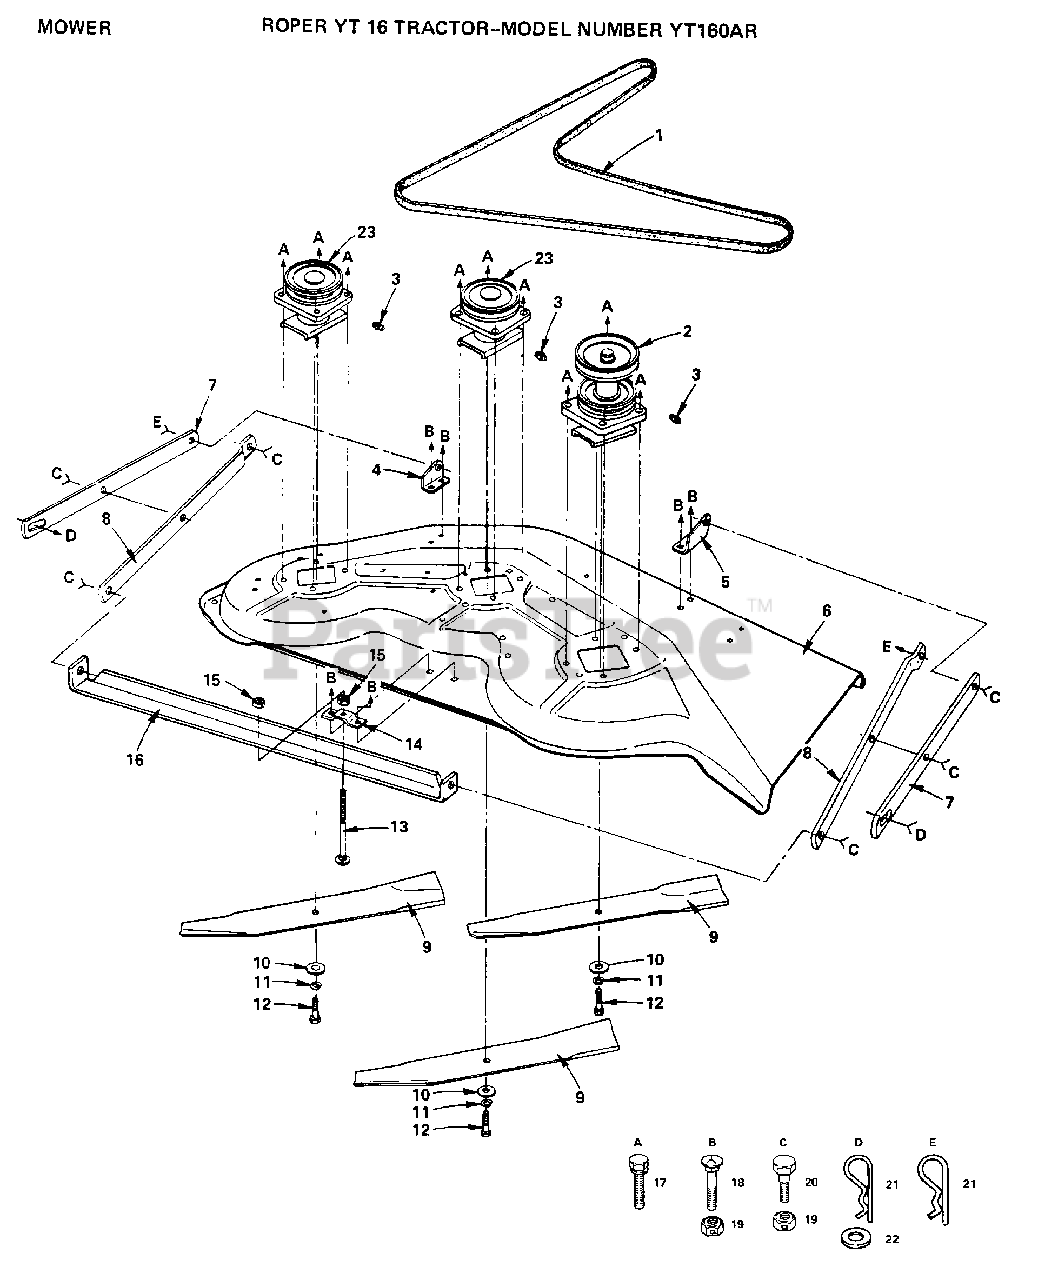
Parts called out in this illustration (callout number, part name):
3	ZERK M
4	BRACKET LH YTV
5	BRACKET RH YTV
7	ARM SUSPENS. LTV
8	ARM SUSPENS. LTV
10	WASHER
11	LOCKWASHER
12	BOLT.3/8-24X1-1/2
15	NUT.HEX.3/8-16UNC
16	CROSSBAR YTV
17	SCREW
18	BOLT
20	BOLT SHOULDER LTV
